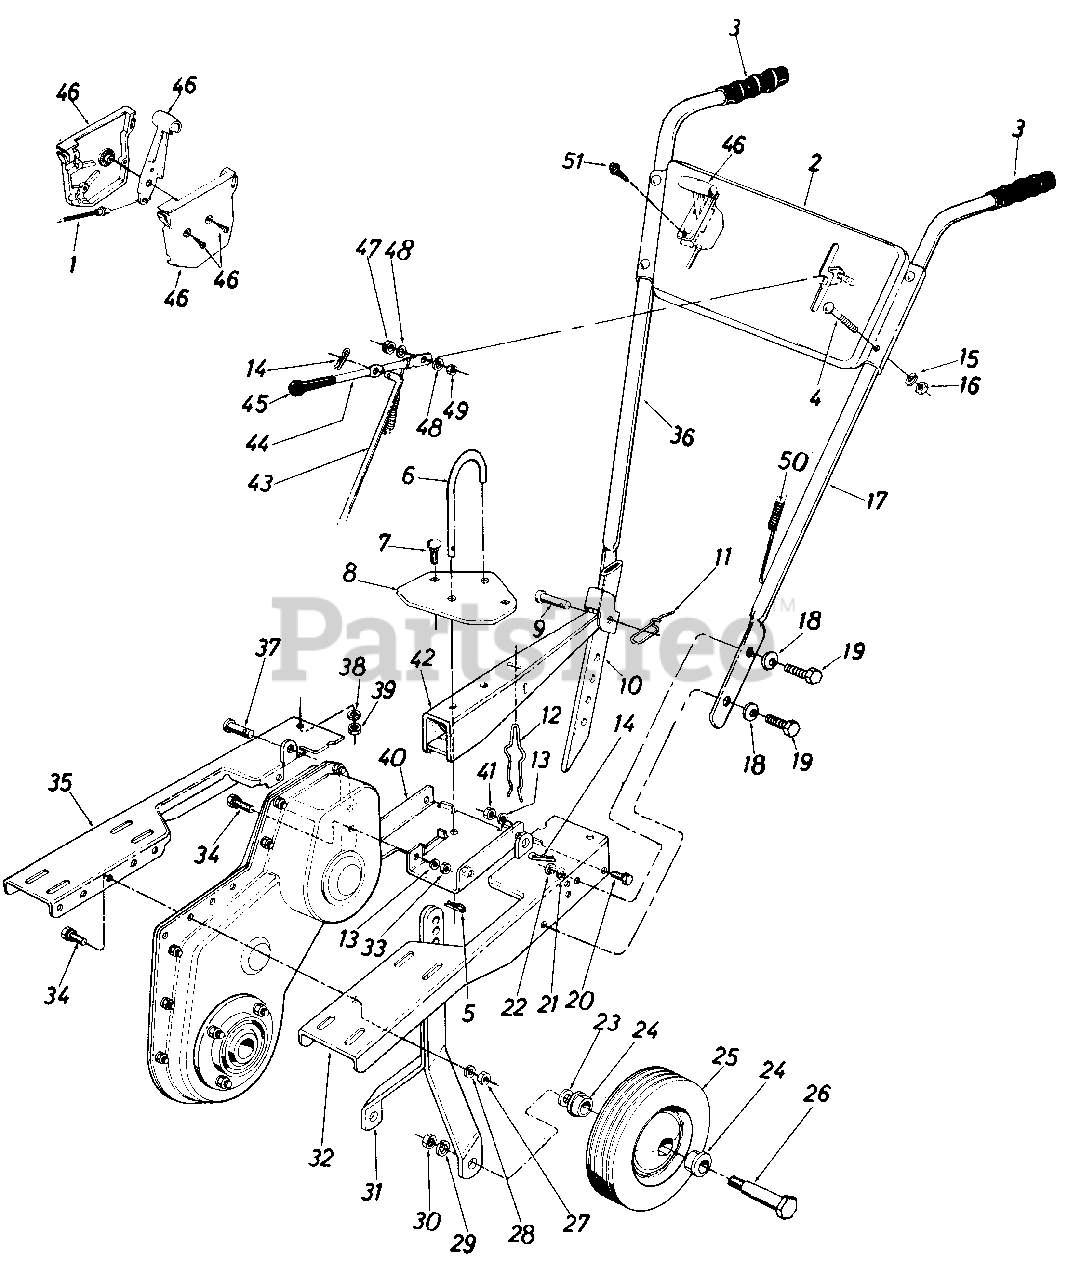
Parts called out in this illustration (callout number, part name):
1	Throttle Control Wire-35"
2	Handle Panel Ass'y.
3	Handle Grip
4	Carriage Bolt 5/16-18 x 1.75" Lg.*
5	Internal Cotter Pin
6	"U"-Clevis Pin .500" Dia.
7	Carriage Bolt 5/16-18 x .75" Lg.
8	"U"-Channel Plate
9	Clevis Pin .500" Dia.
10	Depth Bar
11	Spring Pin
12	Depth Bar Spring
13	L-Wash. 5/16" I.D.
14	Internal Cotter Pin
15	L-Wash. 5/16" I.D.
16	Hex Nut 5/16-18 Thd.
17	Handle-L.H.
18	Belleville Wash. 3/8" I.D.
19	Hex Bolt 3/8-16 x 1.00" Lg.
20	Hex Bolt 5/16-18 x .75" Lg.
21	L-Wash. 3/8" I.D.*
22	Hex Nut 3/8-16 Thd.
23	Belleville Wash. .505 I.D. x 1.00" O.D.
24	Fl. Bearing w/Flats .631 I.D.
25	Wheel Ass'y. Comp. 10 x 1.75
26	Shoulder Bolt .625" Dia. x 2.75" Lg.
27	Hex Nut 5/16-18 Thd.
28	L-Wash. 5/16" I.D.
29	L-Wash. 1/2" I.D.
30	Hex Ins. L-Nut 1/2-20 Thd.
31	Wheel Bracket Ass'y.
32	Engine"U"-Channel Ass'y.-L.H.
33	Hex Nut 5/16-18 Thd.*
34	Hex Sems Bolt 5/16-18 x 1.00" Lg.
35	Engine"U"-Channel Ass'y.-R.H.
36	Handle-R.H.
37	Clevis Pin
38	L-Wash. 5/16 I.D.
39	Hex Nut 5/16-18 Thd.
40	"U"-Channel Bracket Ass'y.
41	Hex Nut 5/16-18 Thd.
42	Tailpiece Ass'y.
43	Control Rod
44	Clutch Lever
46	Throttle Control Box Ass'y.
47	Rubber Wash.
48	Fl-Wash. .344" I.D. x.880 O.D. x .06
49	Hex Cent. L-Nut 5/16-18 Thd.
50	Extension Spring .75 O.D. x 11.0" Lg.
51	Self-Tap Scr. #10 x 1/2" Lg.
